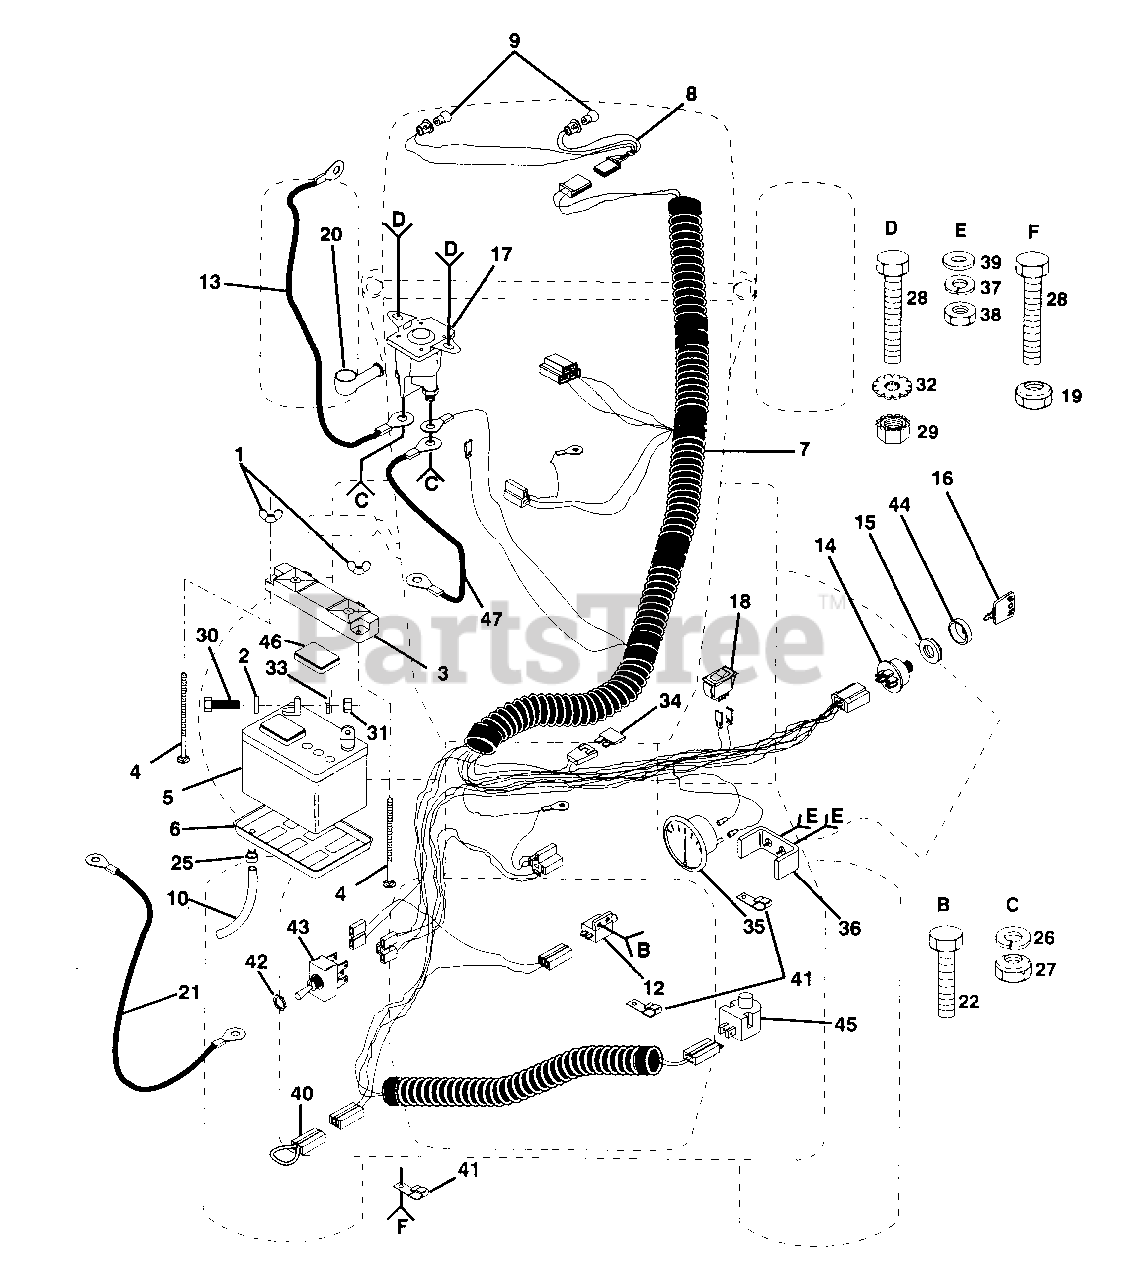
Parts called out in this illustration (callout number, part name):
1	Wingnut 1/4-20 (AYP part number)
2	Washer 9/32 x 5/8 x 16 Gauge (AYP part number)
3	Guard, Terminal (AYP part number)
4	Bolt, Carriage 1/4-20 x 7-1/2 (AYP part number)
5	Battery (AYP part number)
6	Tray, Battery (AYP part number)
7	Harness, Ignition
8	Harness, Light Socket (AYP part number)
9	Bulb, Light (AYP part number)
10	Tube, Battery Tray (AYP part number)
12	Switch, Interlock, Clutch (AYP part number)
13	Cable, Battery (AYP part number)
14	Ignition, Switch (AYP part number)
15	Nut, Ignition (AYP part number)
16	Key, Molded (AYP part number)
17	Solenoid (AYP part number)
18	Switch, Light (AYP part number)
19	Nut, Hex 1/4-20 (AYP part number)
20	Terminal Cover (For Solenoid) (AYP part number)
21	Cable, Battery (Battery to Ground) (AYP part number)
22	Screw, Tapping, Hex Head #10-24 UNC x 1/2 TyF (AYP part number)
25	Clamp, Hose (AYP part number)
26	Washer, Lock 1/4 (AYP part number)
27	Nut, Hex, Jam 1/4-20 (AYP part number)
28	Bolt, Hex 1/4-20 x 1/2 Grade 5 (AYP part number)
29	Nut, Keps, Hex 1/4-20 (AYP part number)
30	Bolt, Hex 1/4-20 x 3/4 (AYP part number)
31	Nut, Hex 1/4-20 (AYP part number)
32	Washer, Lock, External Tooth 1/4 (AYP part number)
33	Washer, Lock 1/4 (AYP part number)
34	Fuse (AYP part number)
35	Ammeter (AYP part number)
36	Bracket, Ammeter (AYP part number)
37	Washer, Lock #10 (AYP part number)
38	Nut (AYP part number)
39	Washer 7/32 x 1/2 x 18 Gauge (AYP part number)
40	Loop, Wire (AYP part number)
41	Clip, Insulated (AYP part number)
42	Nut, Hex (AYP part number)
43	Switch, PTO (AYP part number)
44	Bezel, Ignition (AYP part number)
45	Switch, Plunger (AYP part number)
46	Cap, Battery (AYP part number)
47	Cable, Battery (Battery to Solenoid) (AYP part number)
